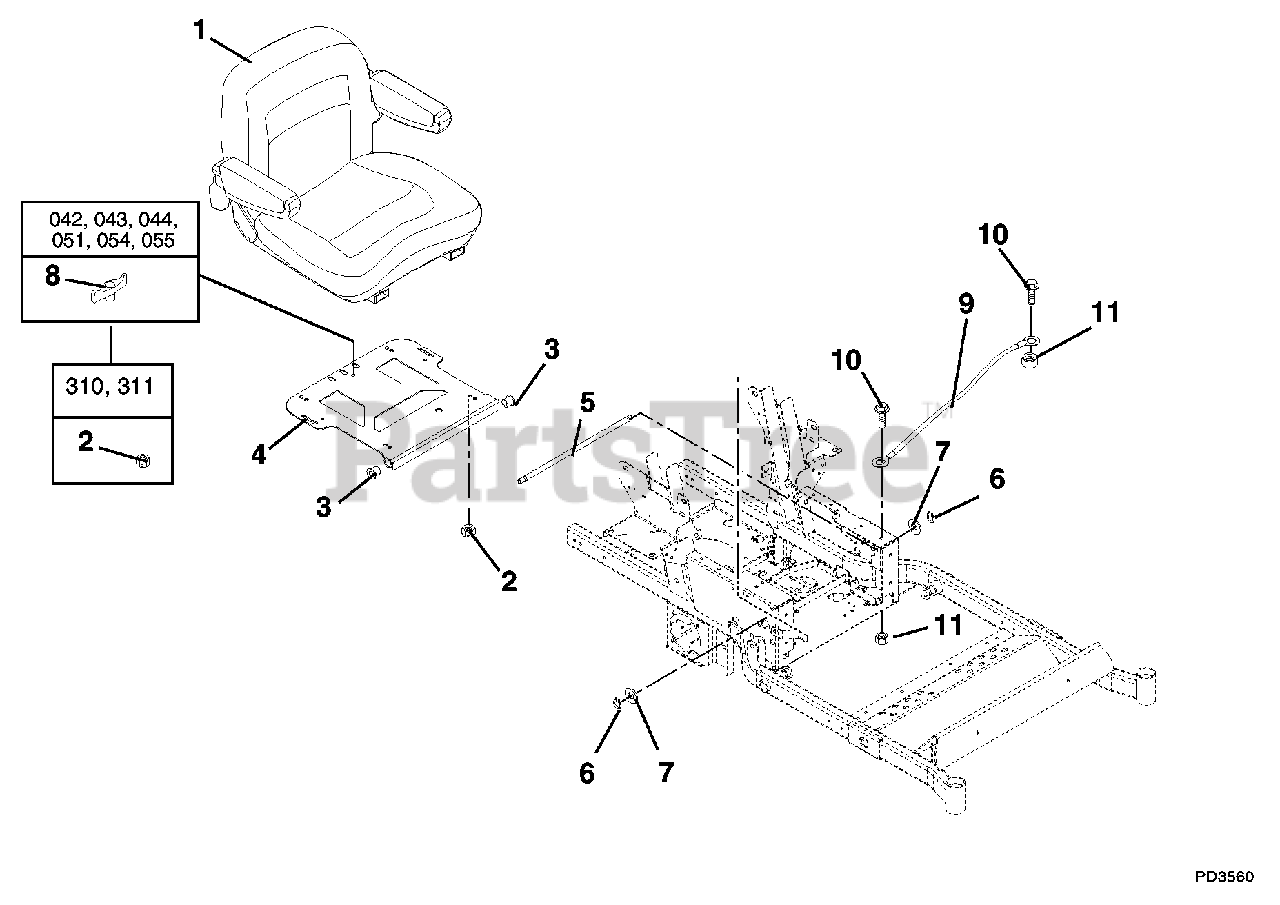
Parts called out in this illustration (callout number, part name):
2	Nut, Locking Top Flange .31-18 (042, 043, 044, 051, 054, 055)
2	Nut, Locking Top Flange .31-18 (310, 311)
3	Bushing, Flange .515 x .750 x .745 x 1.00
4	Seat Pivot Mount
5	Rod, Seat Frame Pivot
6	Ring, Retaining External .500 x .050
7	Washer, Flat Steel .531 x 1.06 x .095
8	Knob, Wing .312-18 (042, 043, 044, 051, 054, 055)
9	Cable, Hood
10	Bolt, Hex .25-20 x .75 Grade 5
11	Nut, Locking Top Flange .25-20
